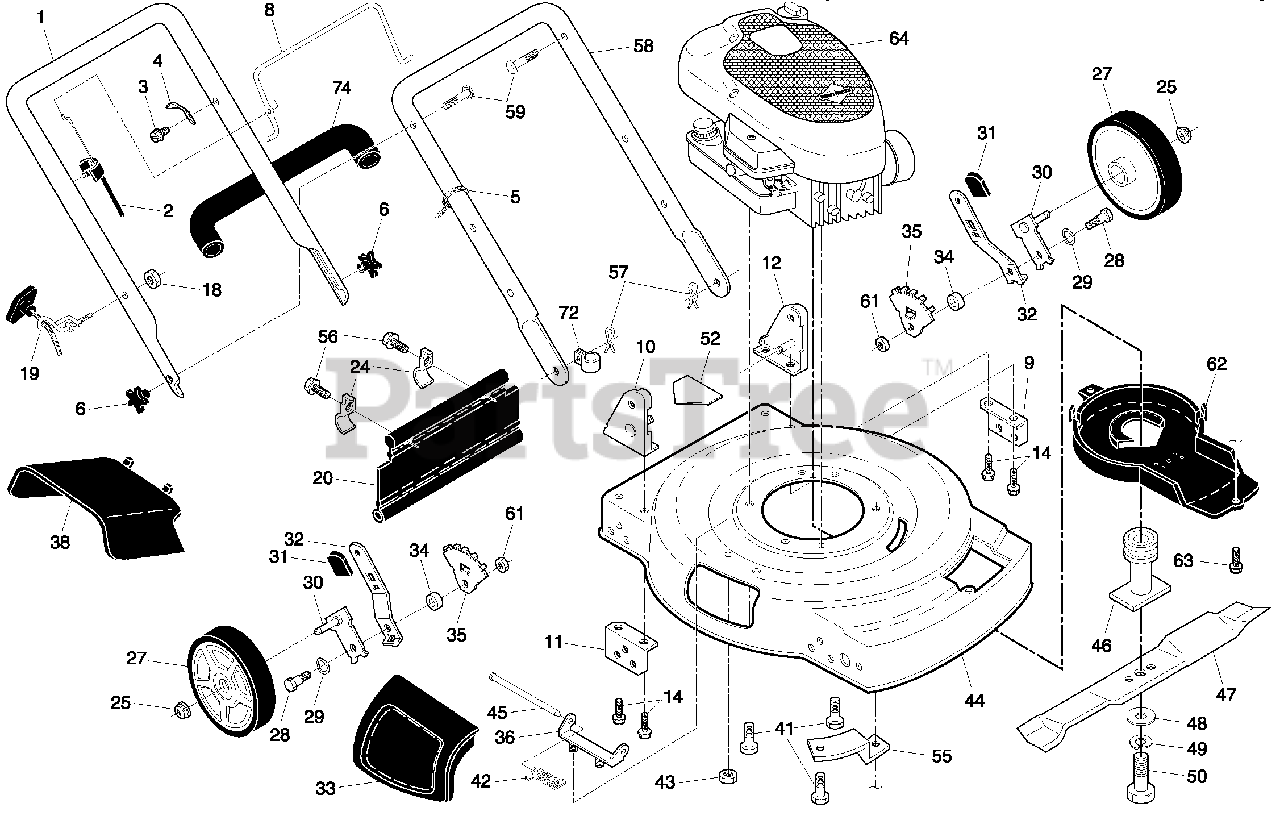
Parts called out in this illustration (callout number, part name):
1	Upper Handle Assembly
2	Engine Zone Control Cable
3	Screw
4	Bracket, Upstop
5	Wire Tie
6	Handle Knob
8	Control Bar
9	Support Bracket, Handle, LH
10	Handle Bracket, RH
11	Support Bracket, Handle, RH
12	Handle Bracket, LH
14	Screw, Thread Cutting 5/16-18 x 3/4
18	Locknut, Keps
19	Rope Guide
20	Kit, Rear Skirt
24	Clamp, Rear Skirt
25	Locknut, Hex 3/18-16
27	Wheel & Tire Assembly
28	Shoulder Bolt
29	Washer, Curved, Cylindrical
30	Axle Arm Assembly
31	Knob, Selector
32	Spring, Selector
33	Mulcher Door
34	Spacer
35	Bracket, Wheel Adjuster
36	Bracket, Housing
38	Deflector, Discharge
41	Screw, Hex Head, Threaded, Rolled 3/8-16 x 1-1/8
42	Spring, Torsion
43	Locknut, Hex 1/4-20
44	Kit, Mower Housing
45	Rod, Hinge
46	Blade Adapter / Pulley
47	Blade, 22"
48	Washer, Hardened
49	Washer, Lock, Helical
50	Screw, Hex Head, Grade 8 3/8-24 x 1-3/8
52	Decal, Danger
55	Mounting Bracket, Debris Shield
56	Screw, Hex Washer Head #10-24 x 1/2
57	Hairpin Cotter
58	Lower Handle
59	Handle Bolt
61	Locknut, Hex
62	Debris Shield
63	Screw
72	Clip, Cable
74	Grip, Foam
